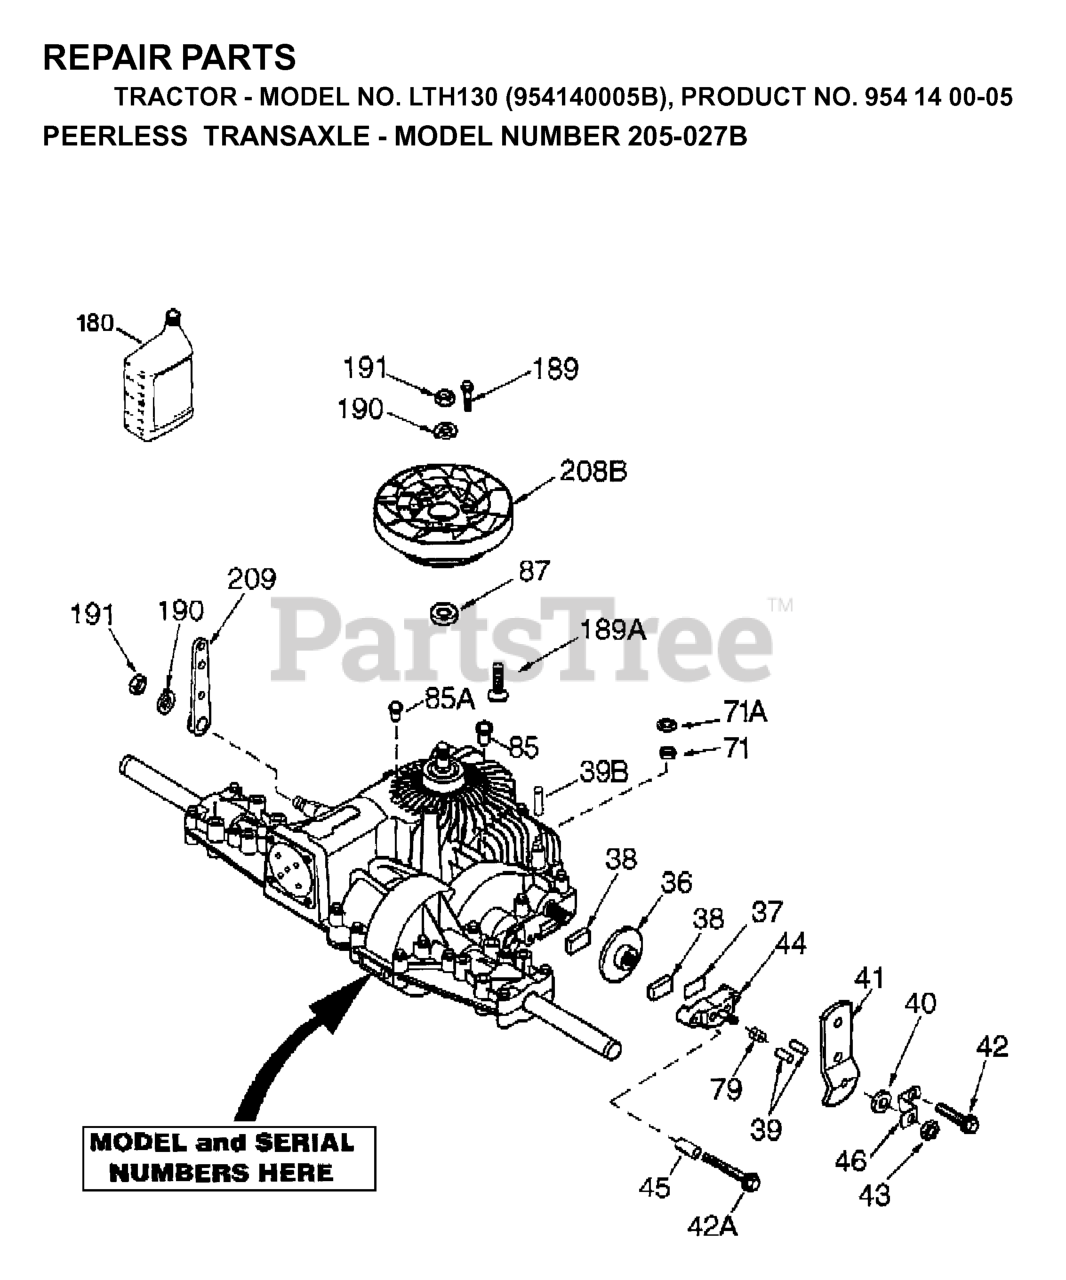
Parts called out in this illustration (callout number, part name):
36	Brake Disk
37	Plate, Brake pad
38	Brake Pad (pkg of 2)
39	Pin, Dowel
40	Washer, Flat
42	Screw, Flanged Hex Head, Thread Forming 1/4-20 x 1-1/4
42A	Screw, 1 /4-20 x 2-1 /4"
43	Lock Nut 5/16-24
44	Holder, Brake pad
45	Spacer (1/2" OD)
71	Seal, Square Cut
79	Piston Assembly
85	Oil Fill Plug
180	Gear Oil 80W90
